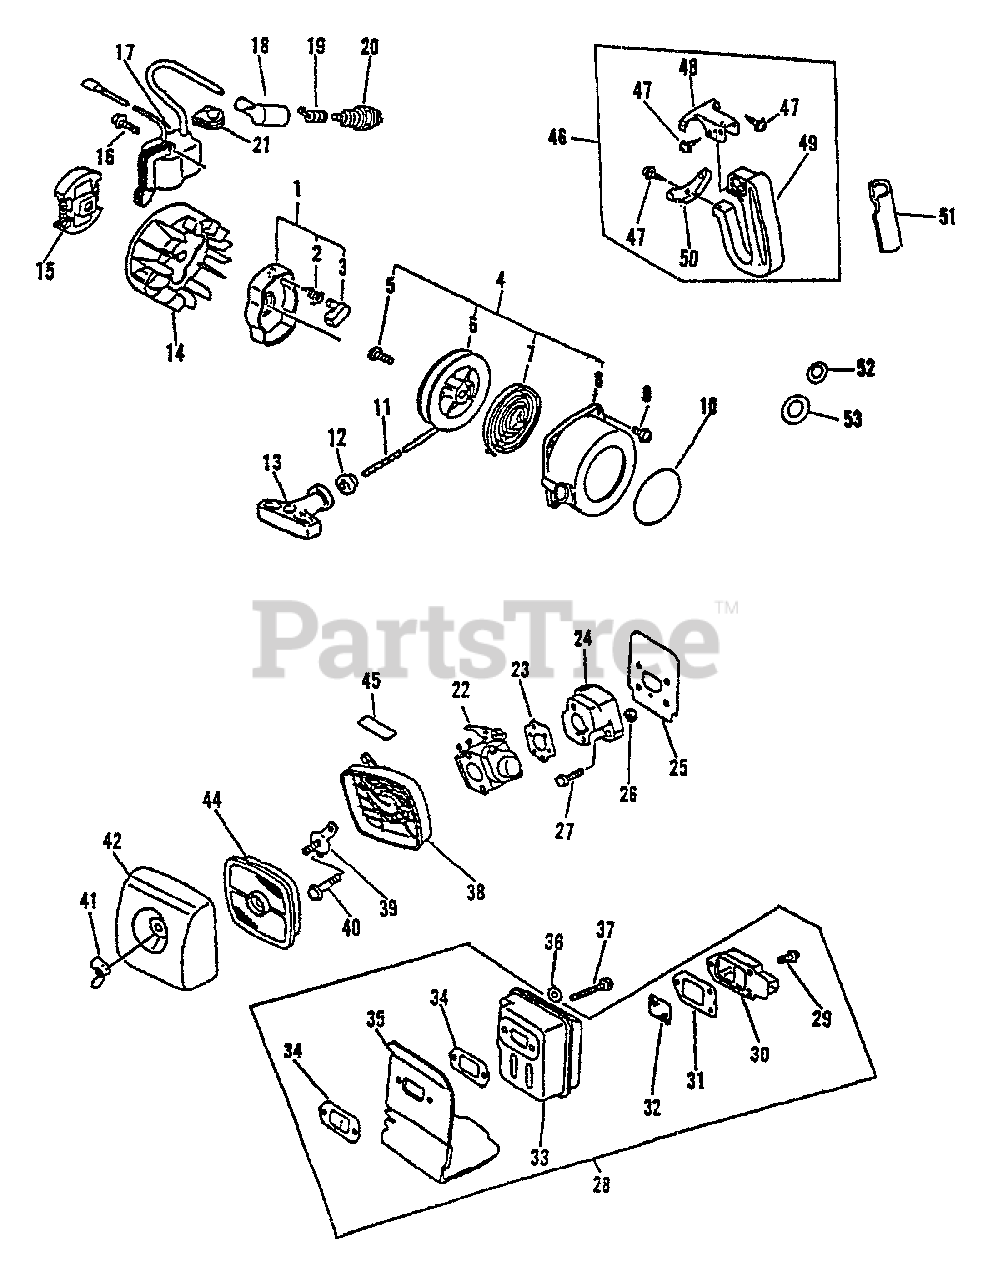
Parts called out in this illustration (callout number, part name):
1	STARTER PAWL ASSY
2	SPRING, RETURN
3	PAWL, STARTER - BLACK
4	STARTER ASSY
6	REEL, ROPE
7	SPRING, REWIND
8	CASE, STARTER - BLUE
9	SCREW - 4X22
10	LABEL - ECHO
11	ROPE, STARTER - 3X990
12	GUIDE, ROPE
13	GRIP, STARTER
14	FLYWHEEL
15	CLUTCH ASSY
16	SCREW - 4X22
17	COIL, IGNITION
18	CAP, SPARK PLUG
19	TERMINAL, SPARK PLUG CAP
20	SPARK PLUG -- BPM-7A
22	CARBURETOR C1U-K16
23	GASKET, INTAKE
24	INSULATOR, INTAKE
25	SHIELD, INTAKE
27	SCREW - 5X20
28	MUFFLER ASSY
29	SCREW - 4X10
30	GUIDE, EXHAUST - OUTER
31	GASKET, EXHAUST
32	SCREEN, SPARK ARRESTOR
33	MUFFLER
34	GASKET, EXHAUST
35	COVER, EXHAUST
36	WASHER - 5
37	SCREW - 5X55
38	AIR FILTER CASE ASSY
39	PLATE, PREVENT
40	SCREW - 5X65
41	WINGNUT - 6
42	COVER, AIR FILTER - GRAY
44	FILTER, AIR - SINGLE LAYER
45	LABEL - CHOKE
46	HANDLE ASSY - REAR
47	SCREW - 5X14
48	BRACKET, HANDLE
49	HANDLE ASSY - REAR
50	BRACKET, HANDLE - LOWER
51	GRIP, HANDLE
